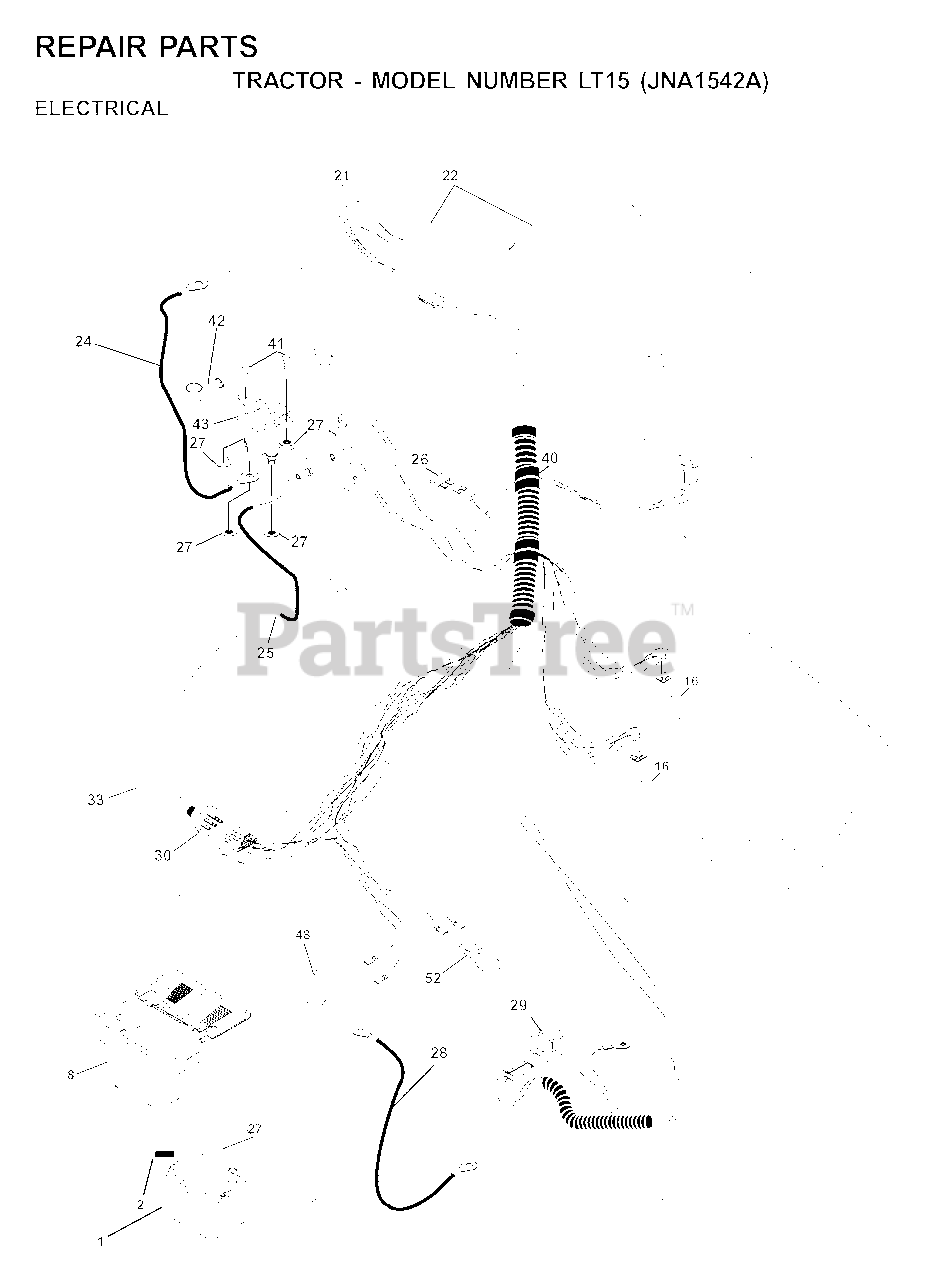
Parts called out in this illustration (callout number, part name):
1	BATTERY 12 VOLT 25 AMP
8	CASE BATTERY MECH HINGE
16	SWITCH INTERLOCK
22	LIGHTBULB
24	BATTERY CABLE GT
25	CABLE BATTERY
26	FUSE 20AMP
27	NUT
28	CABLE T
29	SWITCH SEAT
30	IGNITION SWITCH
33	KEY MLD GEN DELTA
40	HARNESS, IGN. LTH120
42	TERMINAL COVER
43	REPL BY 532 1461-54
52	WIRE PROTECTION LOOP
